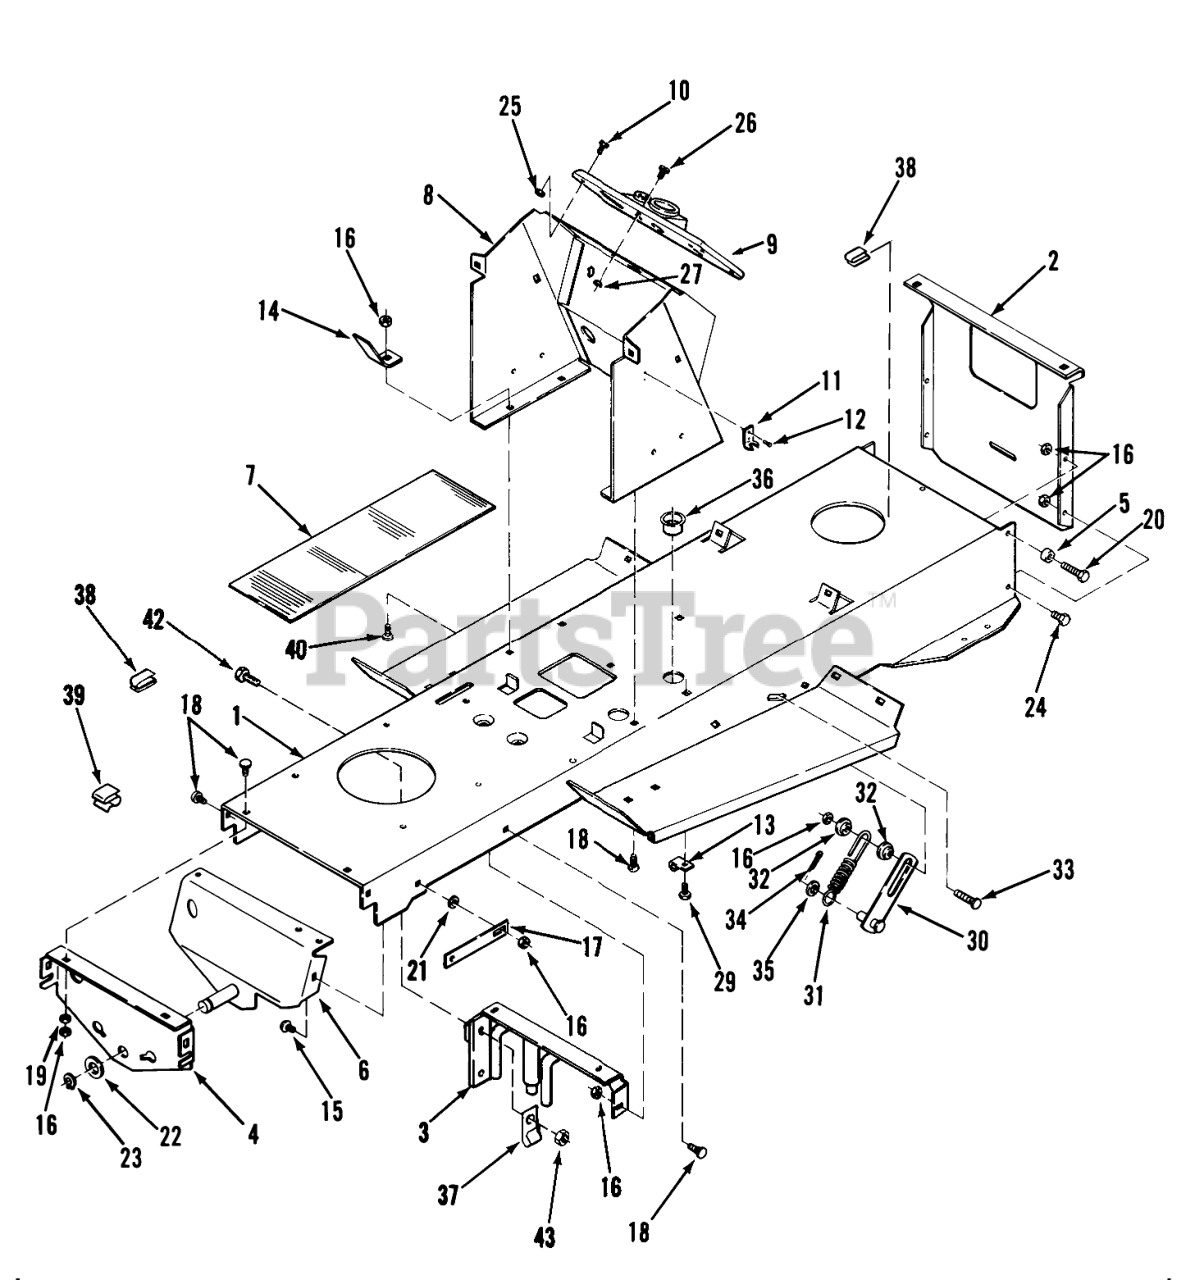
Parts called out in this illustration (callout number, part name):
1	Frame
2	PLATE DRAWBAR
3	Frame Support Plate 208-5
3	ASS'Y-FRAME SUPPO R
4	PLATE SUPT - AXLE R
5	Spacer
6	ASS'Y-AXLE SPT RE R
7	PAD-FOOTREST
8	Hoodstand 211-4
8	HOODSTAND ASSY B
9	CONSOLE
9	Console Panel 212-6
10	SCREW #10X.62 PHCR
11	Latch Keeper
12	RIVET
13	J-CLIP
14	BRACKET FUSE
15	Bolt-Carriage
16	Nut
17	STRAP R
18	Bolt
19	WASHER 5/16 SAE
20	Bolt
21	Washer-Lock
22	WASHER
22	WASHER-SHIM
23	Snap Ring
24	Bolt
25	Nut
26	Screw
27	Nut
29	Bolt
30	ASSY LINK B
31	SPRING
32	BUSHING
33	Bolt-Carriage
35	WASHER
36	BUSHING-NYLON 1.093
37	CLIP
38	RETAINER
39	CLIP-CABLE
40	Bolt
42	Bolt
43	NUT
